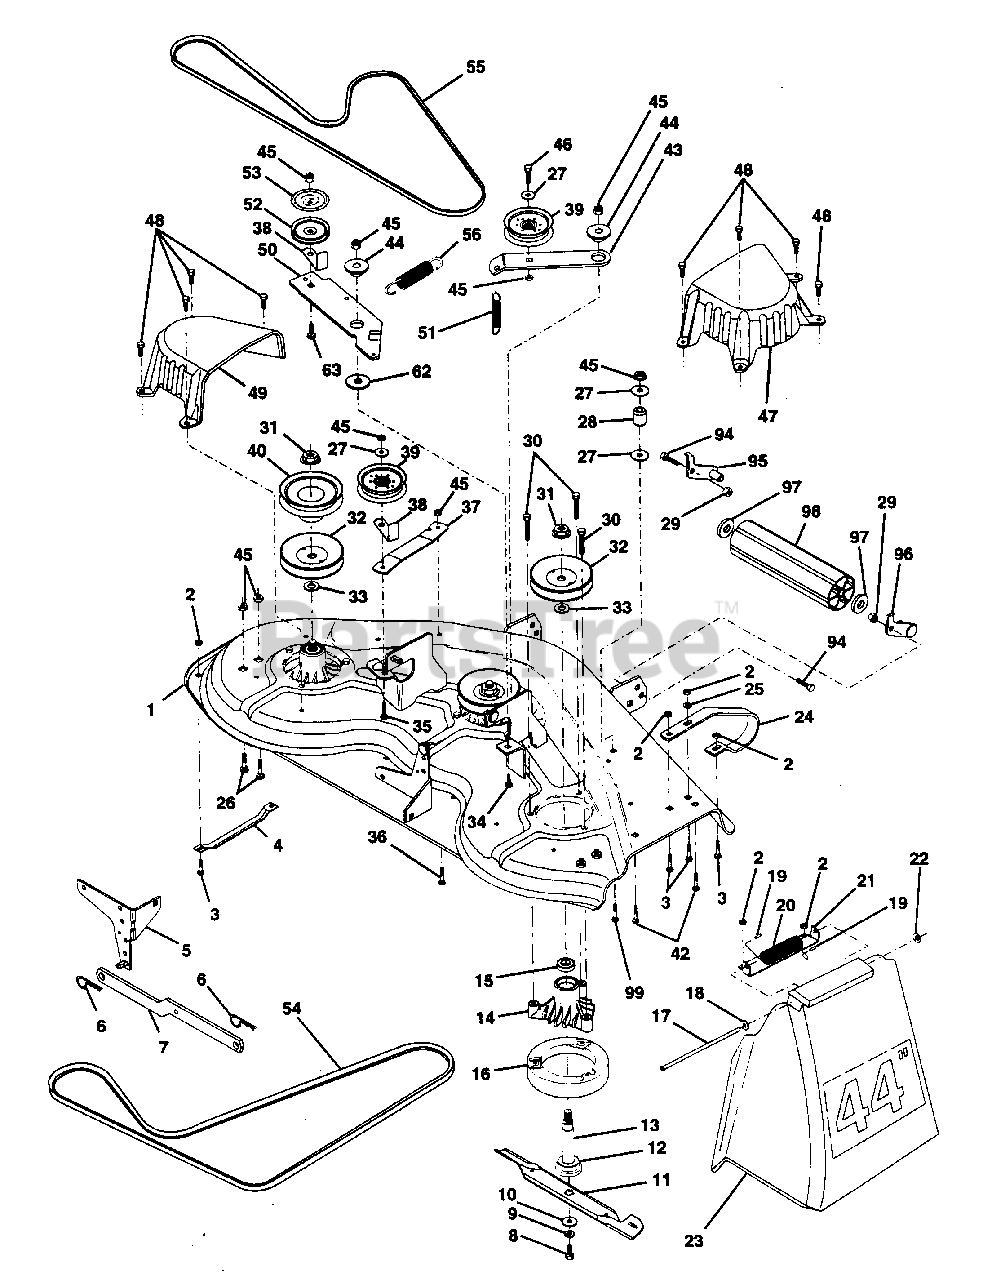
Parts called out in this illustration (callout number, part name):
1	Deck Asm., Mower 44" Vented (AYP part number)
2	Nut, Crownlock 5/16-18 Unc
3	Bolt, Carriage 5/16-18 x 3/4 (AYP part number)
4	Runner, Mower LH (AYP part number)
5	Bracket Asm., Sway Bar (AYP part number)
6	Retainer, Spring (AYP part number)
7	Arm Suspension, Rear (AYP part number)
8	Bolt 3/8-24 x 1.25 Gr. 8 Patched (AYP part number)
9	Washer, Lock Hvy 3/8 Unplated (AYP part number)
10	Washer, Hard Blade Mower Vented (AYP part number)
11	Blade (3 Required) (AYP part number)
12	Bearing, Ball #6204 (Mandrel) (AYP part number)
13	Shaft Asm., W/Lower Brg (Inc. 12) (AYP part number)
14	Housing, Mandrel 44" Vent (AYP part number)
15	Bearing, Ball Mandrel (AYP part number)
16	Stripper, Mower Vented (AYP part number)
17	Rod, Hinge (AYP part number)
18	Washer 11/32 x 5/8 x 16 Ga. (AYP part number)
19	Cap, Sleeve (AYP part number)
20	Spring, Torsion Deflector (AYP part number)
21	Bracket, Deflector (AYP part number)
22	Nut, Push (AYP part number)
23	Shield, Deflector Mower (AYP part number)
24	Runner, RH (AYP part number)
25	Washer 11/32 x 3/4 x 16 Ga. (AYP part number)
26	Bolt Carriage 3/8-16 x 3/4 (AYP part number)
27	Washer 13/32 x 13/16 x 16 Ga. (AYP part number)
28	Spacer, Spring Stop Idler
29	Nut, Lock Hex W/Wsh 3/8-16 Unc (AYP part number)
30	Screw Thdrol. Hex Hd Zinc Mower (AYP part number)
31	Nut, Flg Top Lock Cntr 9/16
32	Pulley, Mandrel (AYP part number)
33	Washer, Spacer Mower Vented (AYP part number)
34	Bolt, Carriage 3/8-16 x 1-1/4 (AYP part number)
35	Bolt, Carriage 3/8-16 x 2 (AYP part number)
36	Bolt, Carriage 3/8-16 x 1 Gr. 5 (AYP part number)
37	Stiffener, Arm Idler (AYP part number)
38	Keeper, Belt Idler (AYP part number)
39	Pulley, Idler Flat (AYP part number)
40	Pulley, Driven (AYP part number)
42	Bolt, Carriage 5/16-18 Unc x 3/4
43	Arm, Idler Secondary (AYP part number)
44	Spacer, Retainer (AYP part number)
45	Nut, Crownlock 3/8-16 Unc
46	Bolt, Fin Hex 3/8-16 Unc x 1-3/4 (AYP part number)
47	Cover, Mandrel RH (AYP part number)
48	Screw, Thd Roll 1/4-20 x 5/8 (AYP part number)
49	Cover, Mandrel LH (AYP part number)
50	Arm, Idler Primary (AYP part number)
51	Spring, Secondary (AYP part number)
52	Pulley, Idler V Groove (AYP part number)
53	Shield, Idler (AYP part number)
54	V-Belt, Mower Primary
55	V-Belt, Mower Secondary (AYP part number)
56	Spring, Primary (AYP part number)
62	Washer Hardened (AYP part number)
63	Bolt Carriage 3/8-16 x 1-1/2 (AYP part number)
94	Bolt Hex 3/8-16 x 1 (AYP part number)
95	Bracket Asm. Noseroller LH
96	Bracket Asm. Noseroller RH
97	Washer 17/32 x 7/8 x 16 Ga. (AYP part number)
98	Roller, Nose
99	Bolt, Carriage 3/8-16 x 1-3/4 Gr. 5 (AYP part number)
